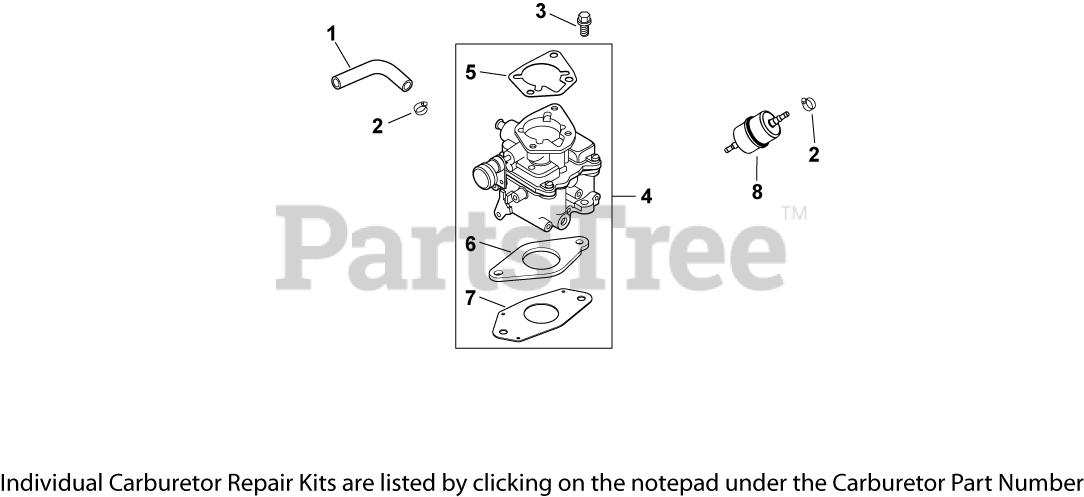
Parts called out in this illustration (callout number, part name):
1	HOSE,LW PERM.FUEL 24.00"-USE 25 111 81-S
2	CLAMP, HOSE (KM)-USE 25 237 31-S
3	SCREW, FLG M6X1.0X25
4	KIT, CARBURETOR W/GASKETS
5	GASKET, AIR CLEANER BASE
6	GASKET, CARBURETOR
7	GASKET, CARBURETOR
8	FILTER, FUEL
